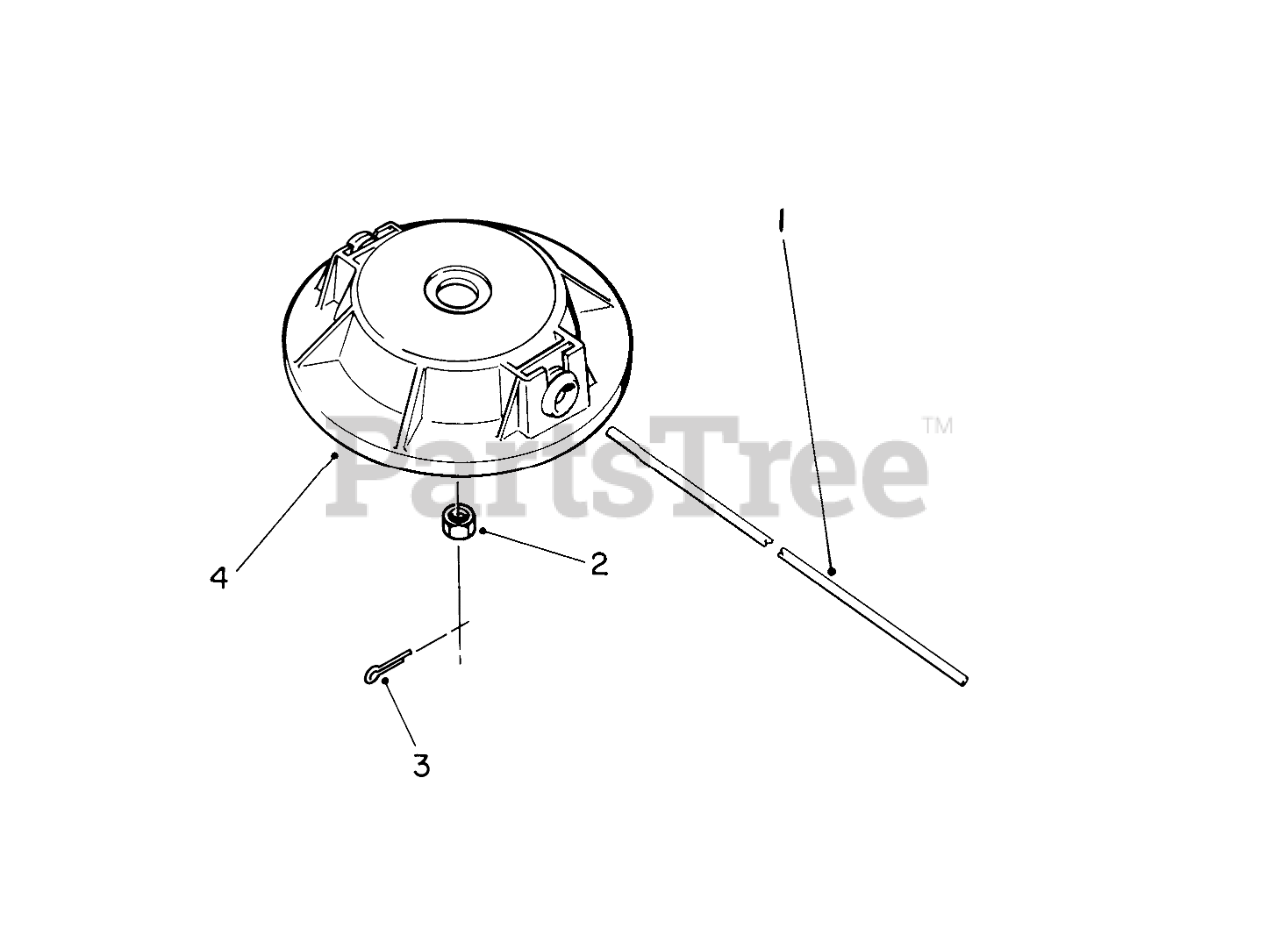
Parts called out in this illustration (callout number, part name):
1	Line-Cutting .105 Dia.
3	1/16 X 1 LG COTTER PIN
4	CUTTER HEAD-PLASTIC
